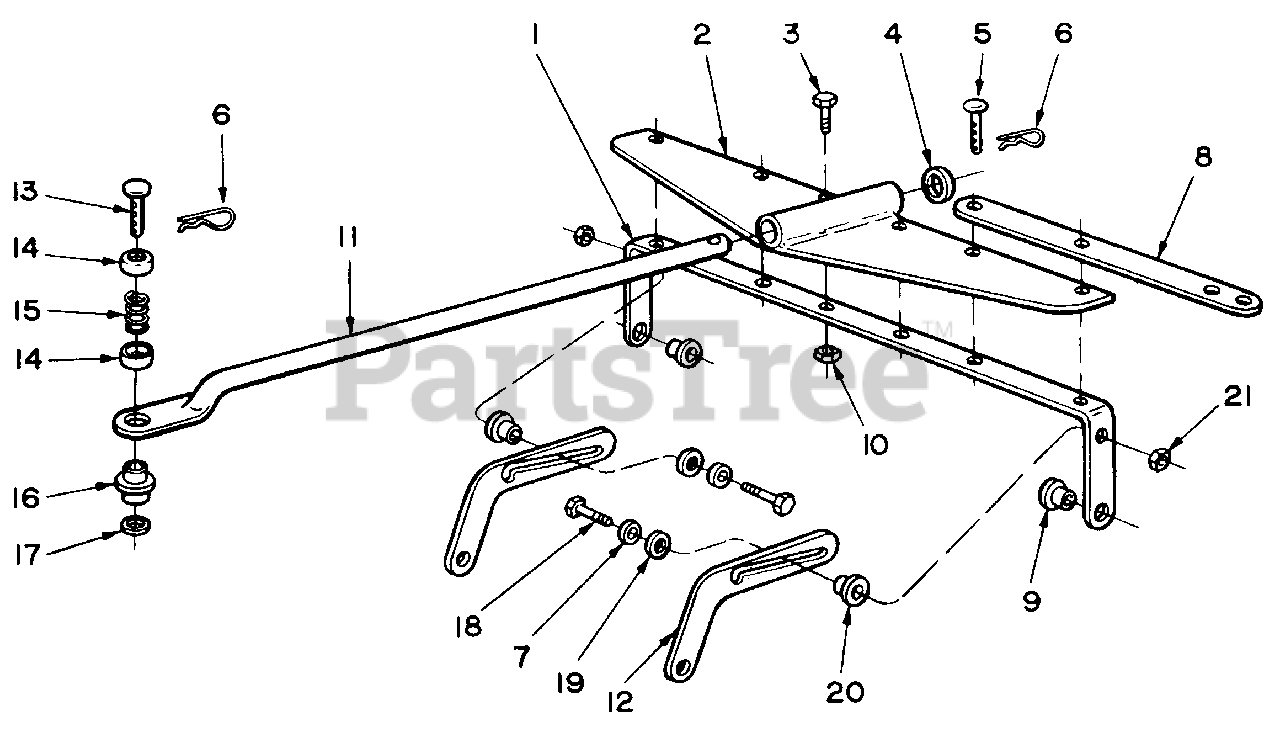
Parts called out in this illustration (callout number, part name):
1	Bridge
2	Tow Bar Plate Ass'y.
3	Bolt 5/16 x 18 x 1
4	Washer
5	Clevis Pin
6	Cotter Pin
7	Washer-Special
8	Outrigger Bar
9	Spacer Bushing
10	Nut 5/16-18
11	Tow Bar Ass'y.
12	Transport Brkt.
13	Clevis Pin
14	Spring Cup
15	Spring
16	Bushing
17	Washer 11/32 x 7/8
18	Shoulder Bolt
19	Washer
20	Spacer
21	Hex L-Nut 1/4-20
